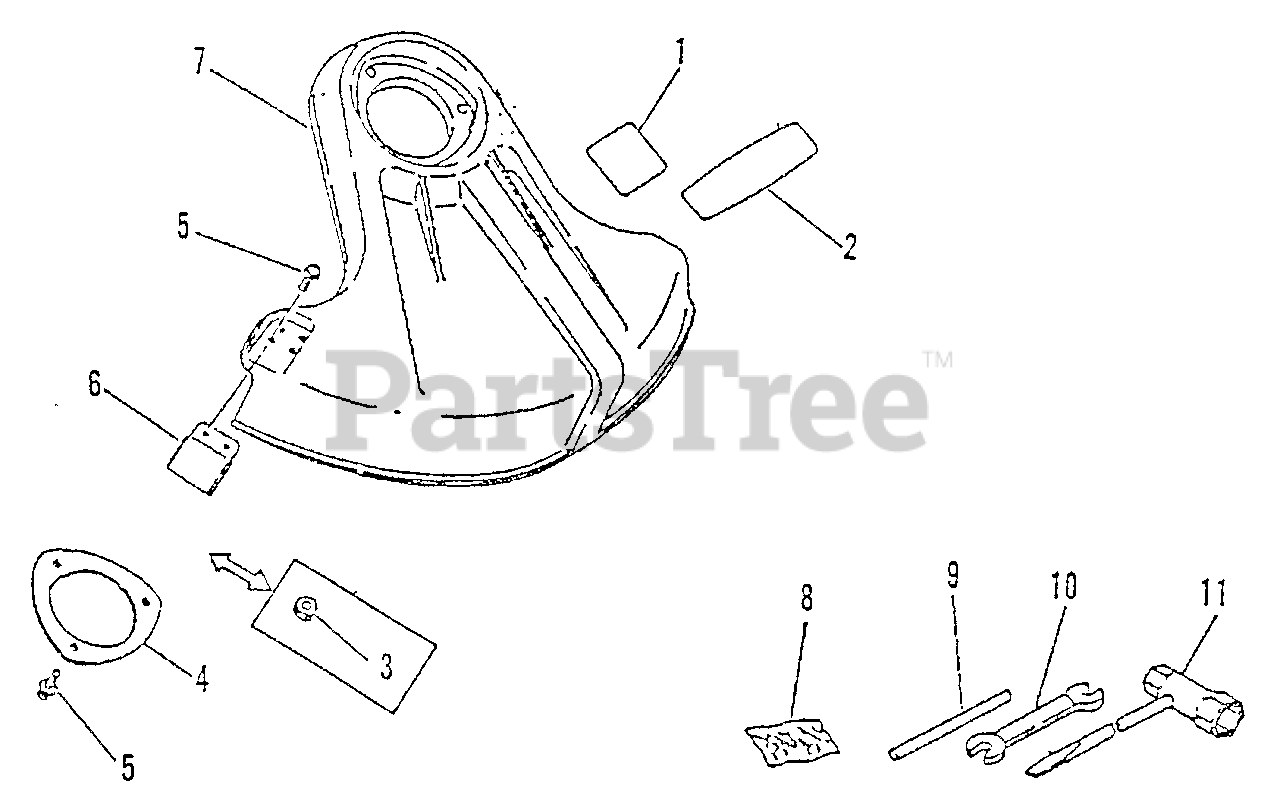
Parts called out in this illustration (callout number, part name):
1	LABEL, CAUTION
2	LABEL, ECHO
3	NUT M5
4	PLATE, SHIELD Ø49.5 MM
5	SCREW 5×16
6	CUTTER, LINE
7	DEBRIS SHIELD ASSY
8	PIN, COTTER 2×22 (PKG. OF 10)
9	TOOL, LOCKING 5×120 MM
10	SPANNER 8×10
11	T-WRENCH 17x-19 L200
